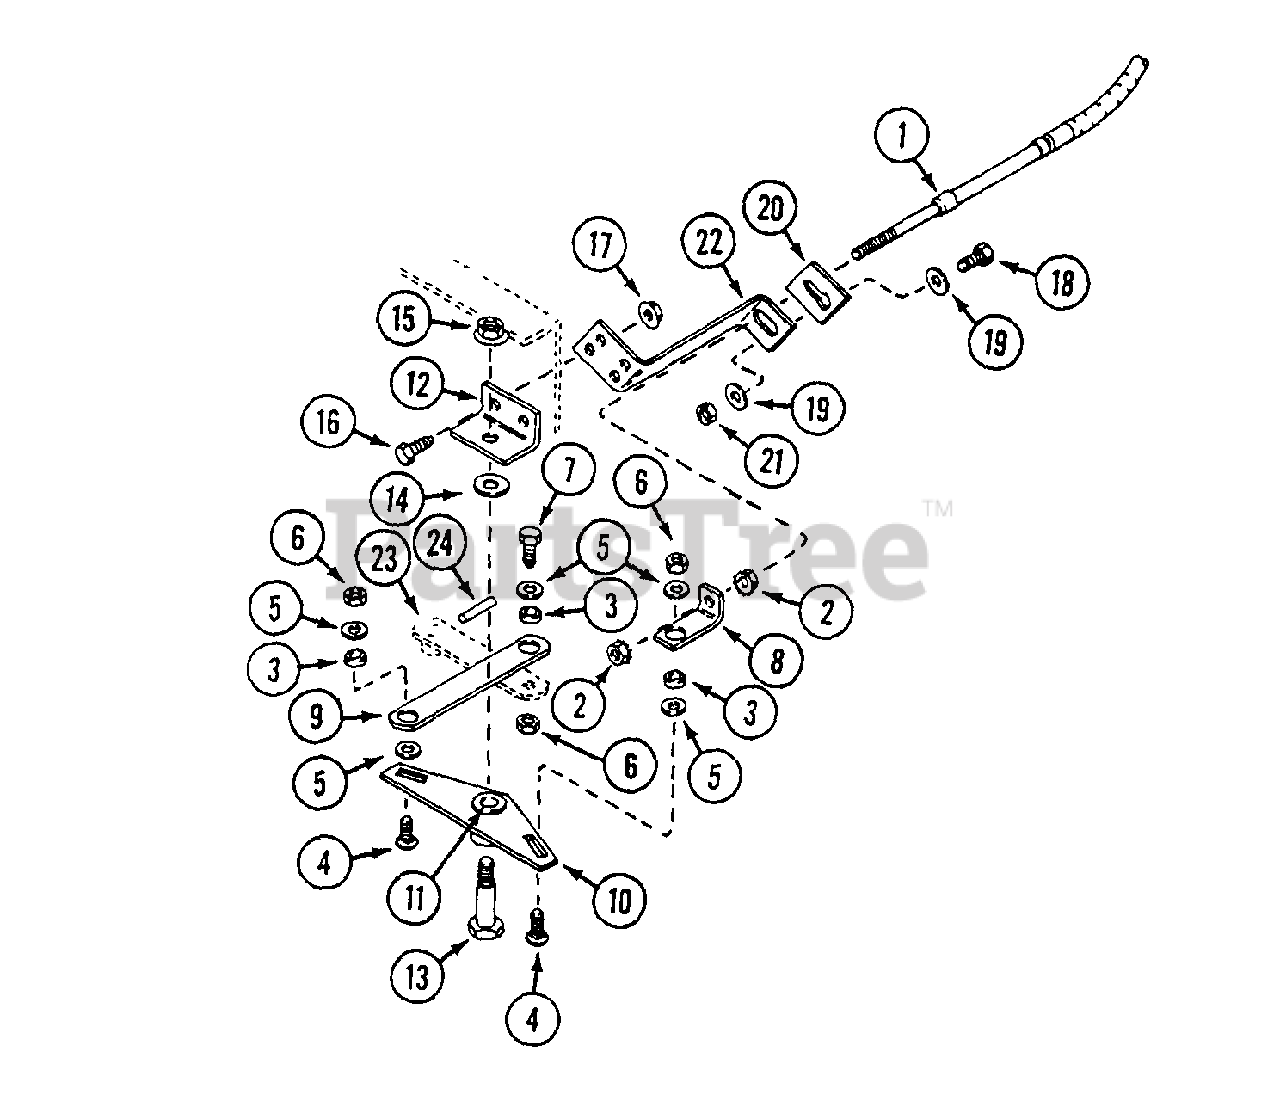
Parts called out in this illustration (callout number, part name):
1	CABLE - steering 46"
2	NUT - #10 - 32
3	BUSHING - steering cable
4	BOLT - 1/4" - 20 x 1" carriage
5	WASHER - 1/4"
6	NUT - 1/4" - 10
7	BOLT - 1/4 - 20 x 1"
8	BRACKET - steering cable end
9	LINK - control cable
12	BRACKET - bellcrank mounting
13	BOLT - shoulder
14	WASHER - 1/2"
15	NUT - 3/8" - 16 flange lock
16	BOLT - 5/16" - 18 x 1"
17	NUT - 5/16 - 18
18	BOLT - 1/4" - 20 x 1"
19	WASHER - 1/4"
20	PLATE - cable mounting
21	NUT - 1/4" - 20 lock
22	BRACKET - cable mounting
23	ARM - transmission
